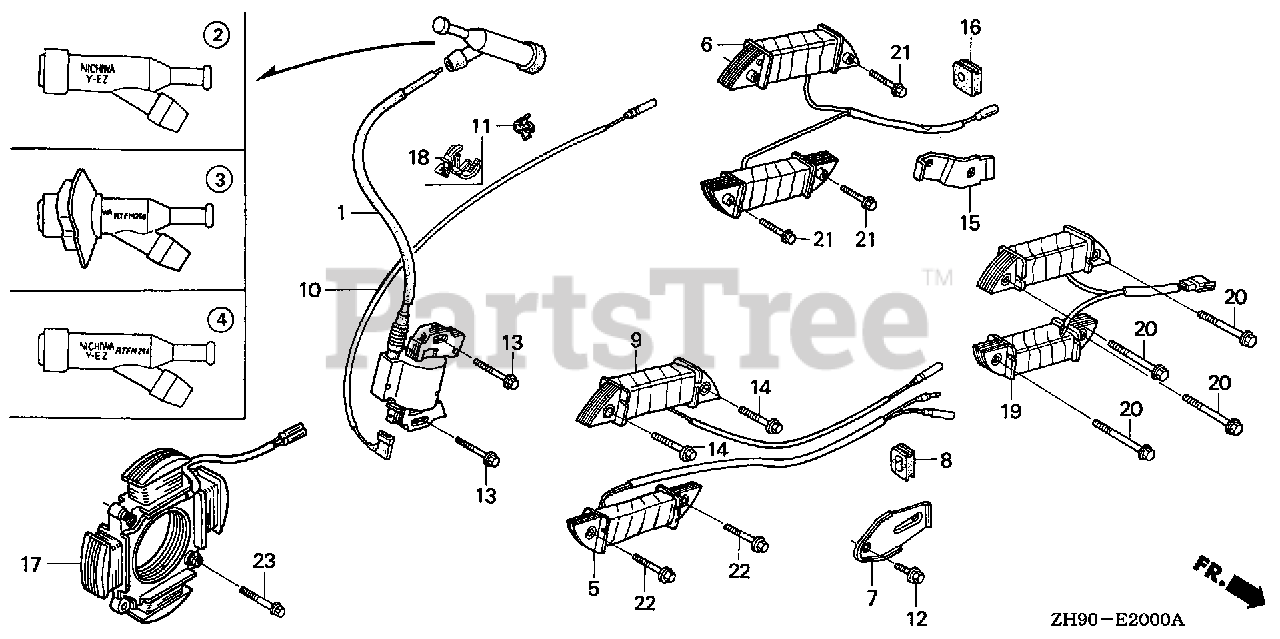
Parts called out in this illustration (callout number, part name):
1	COIL ASSY., IGNITION
4	CAP ASSY., NOISE SUPPRESSOR (NICHIWA Y-EZ RTFM256)
8	GROMMET, WIRE
10	WIRE, STOP SWITCH (370MM)
11	HOLDER, STOP SWITCH WIRE
13	BOLT, FLANGE (6X28) (CT200)
